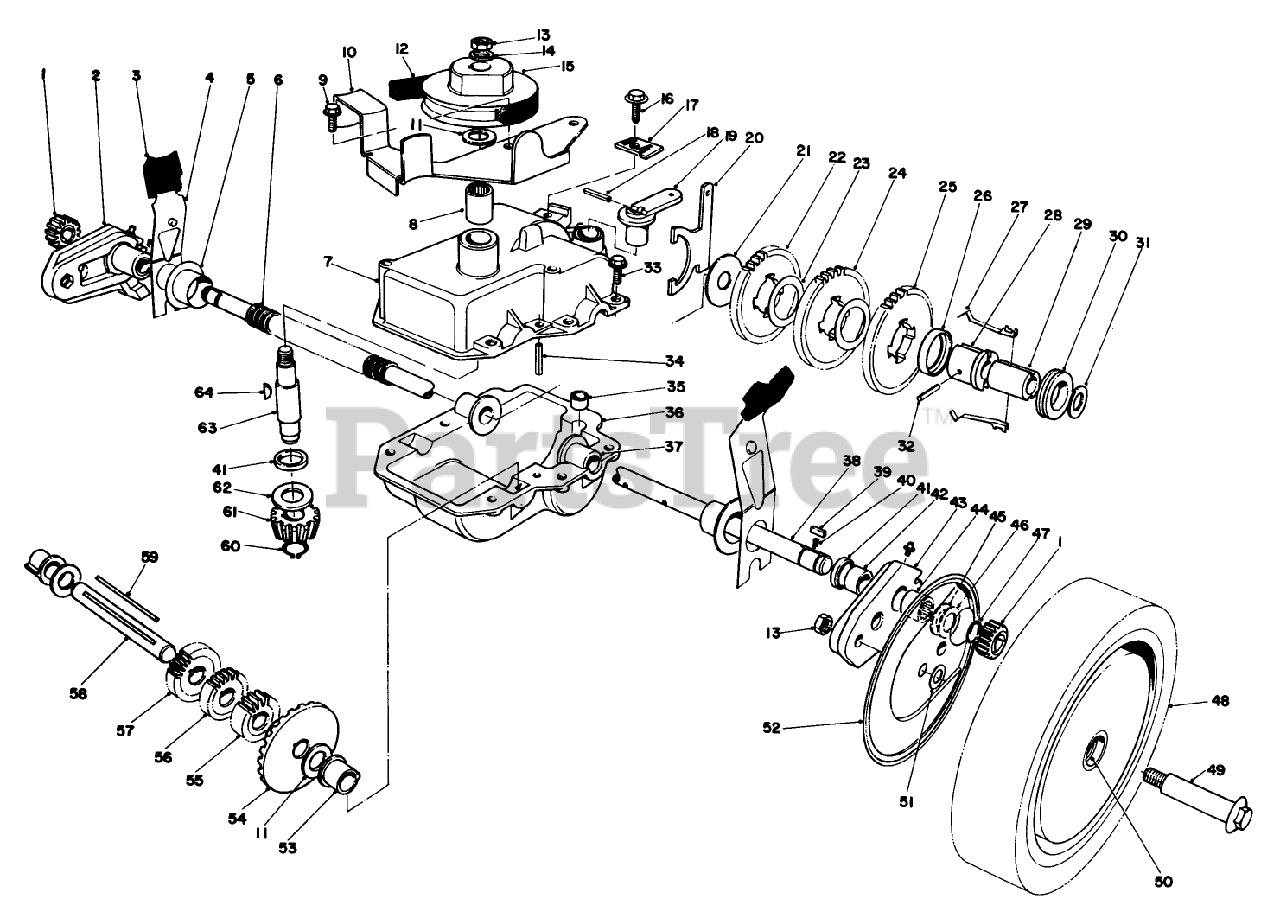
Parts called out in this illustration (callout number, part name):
1	GEAR-PINION
3	KNOB-ARM
4	SPRING ARM ASM SP
5	CAP-END
6	CONDUIT-CONVOLUTED, SPLIT
7	DISC PRC4
9	SCREW
11	Washer
12	V-BELT
14	WASHER-FLAT
15	PULLEY
16	SCREW-THD ROLL, HWH
18	PIN-SPRING
19	LEVER-SHIFT
21	WASHER
22	GEAR-38T
23	WASHER
24	GEAR-42T
29	SLEEVE
30	COLLAR-SHIFT
31	WASHER-PLAIN
33	Screw-Tapping
34	ROLL PIN 3/16 X 1 IN
35	BUSHING-YOKE
39	KEY RECTANGULAR
40	SPRING-COMPRESSION
42	Bushing
47	RING-RETAINING
49	BOLT-WHEEL
50	BUSHING
51	WASHER
52	WHEEL COVER
53	BUSHING
55	GEAR-12T
56	GEAR-14T
57	GEAR-18T
60	RING-RETAINING
61	PINION-BEVEL
63	Input Shaft
64	KEY-WOODRUFF
